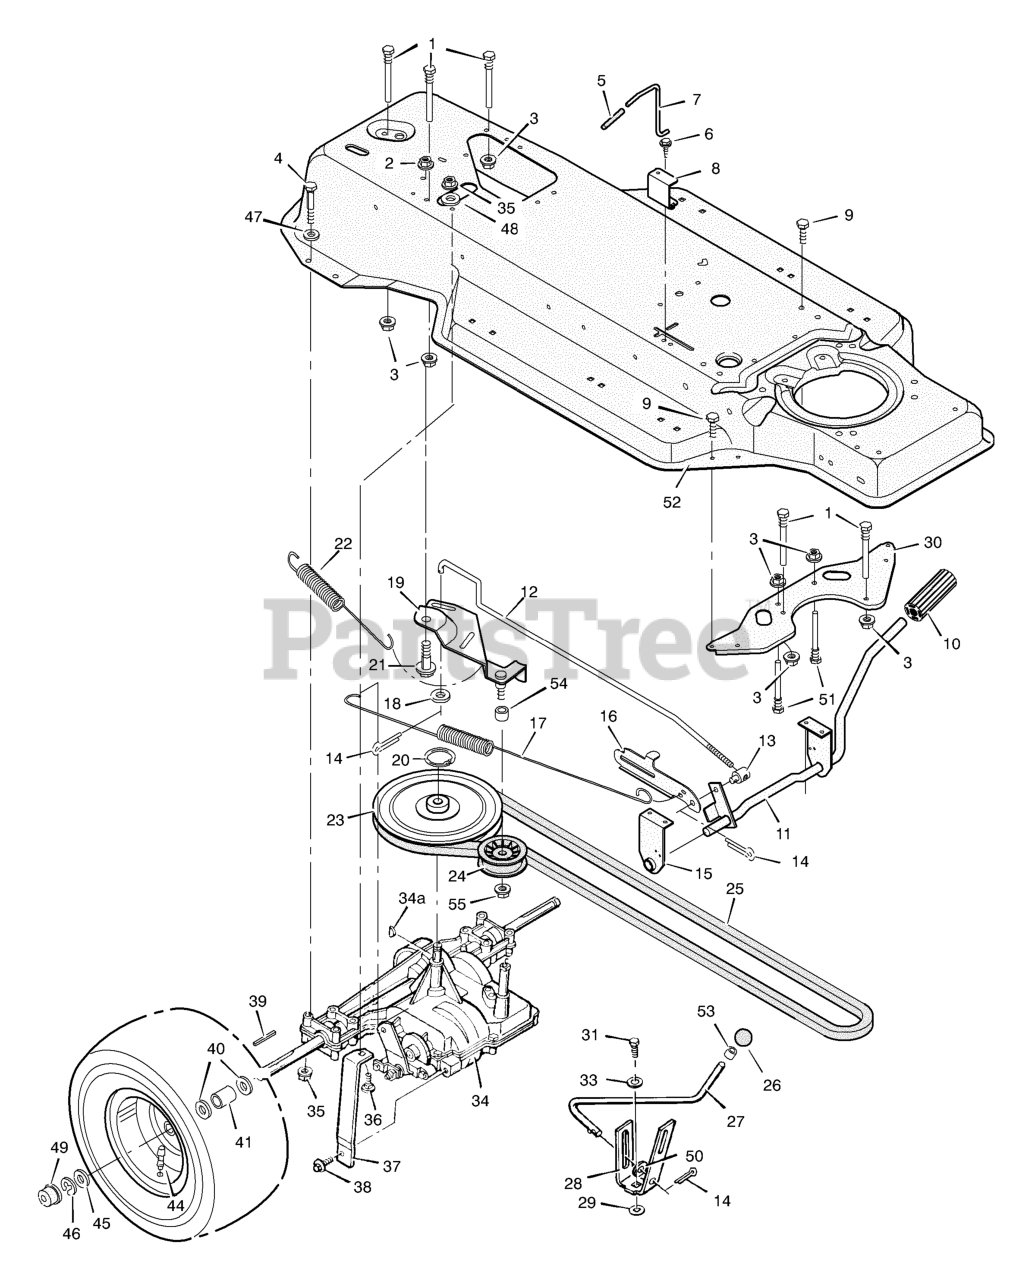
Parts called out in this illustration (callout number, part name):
1	Guide, Belt
2	Locknut, Flange
3	Nut, Flange
4	Bolt, Hex
7	Rod, Control -Park Brake
8	Guide, Bracket
10	Clutch and Brake Pedal
11	Lever Assembly
12	Rod, Clutch
13	Nut, Adjustable
14	Pin, Cotter
15	Bracket, Support
16	Latch, Park Brake
17	Spring, Brake Extension
18	Washer
19	Bracket Assembly, Idler
20	Ring, Retainer
21	Bolt, Shoulder
22	Spring, Drive Extension
23	Pulley, Motion Drive
24	Pulley, Backside Idler
25	Belt, Motion Drive
26	Knob, Shift Lever
27	Lever, Shift
28	Yoke, Shift
30	Plate, Belt Guide
31	Bolt, Hex
34	Transaxle, Peerless **
35	Nut, Flange
36	Bolt, Carriage
37	Support, Transaxle
39	Key, Square
41	Spacer, Transaxle
43	Wheel & Tire Assembly
44	Stem, Valve
47	Washer
49	Hub Cap
50	Washer
51	Guide, Belt
52	Frame Assembly
53	Ring, Tolerance
55	Nut
